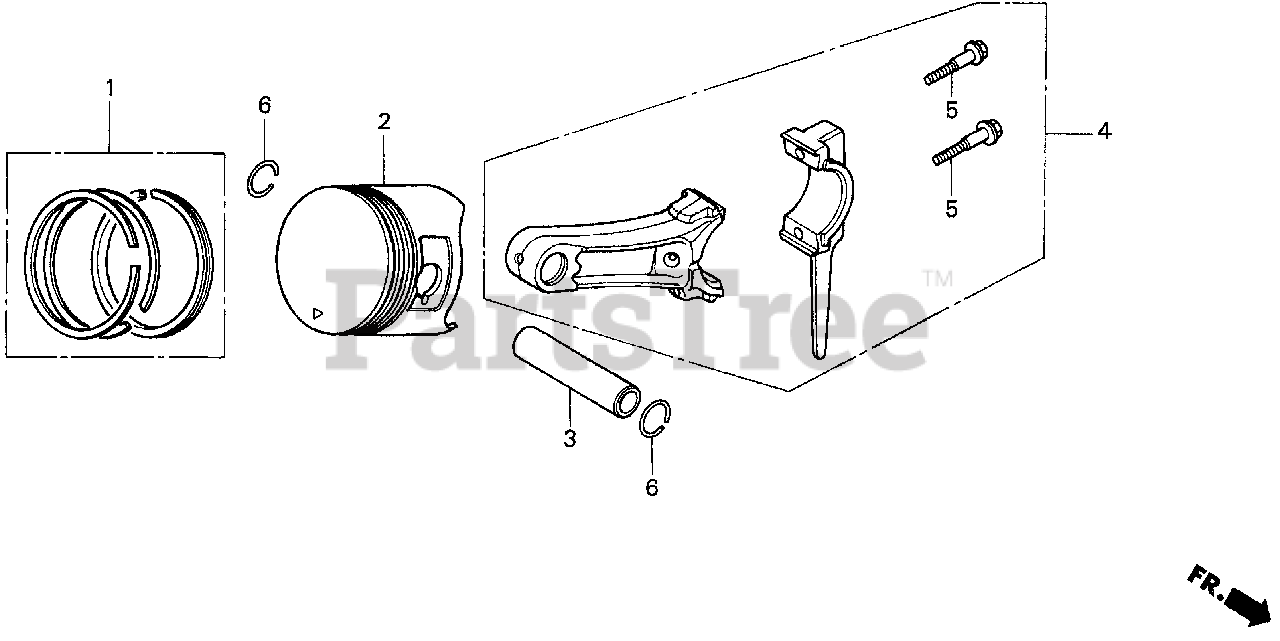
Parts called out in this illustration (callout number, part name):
1	RING SET, PISTON (STD)
1	RING SET, PISTON (OS 0.25)
1	RING SET, PISTON (OS 0.50)
1	RING SET, PISTON (0.75)
2	PISTON (STD)
2	PISTON (OS 0.25)
2	PISTON (OS 0.50)
2	PISTON (0.75)
3	PIN, PISTON
4	ROD ASSY., CONNECTING (UNDER SIZE)
4	ROD ASSY., CONNECTING
5	BOLT, CONNECTING ROD
6	CLIP, PISTON PIN (13MM)
